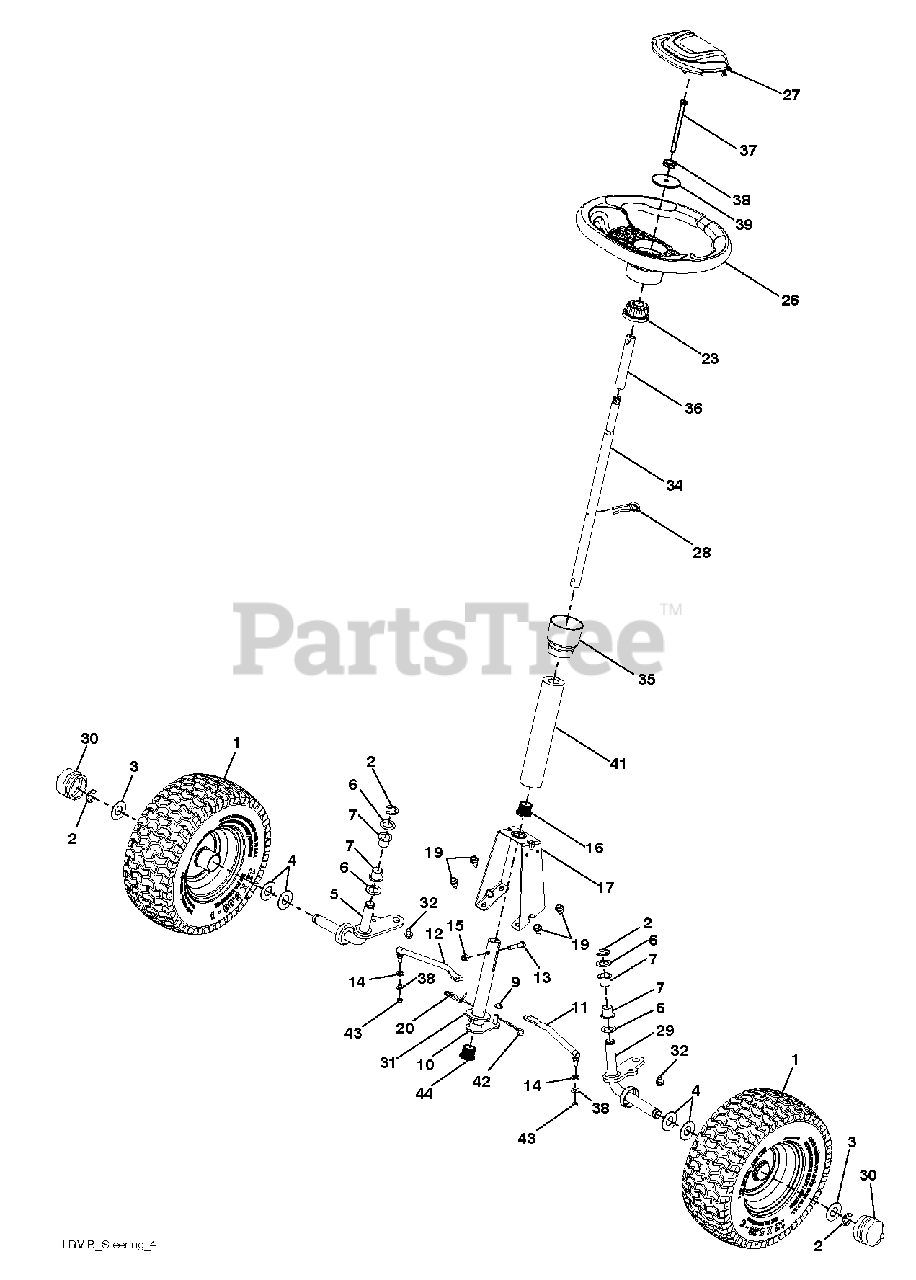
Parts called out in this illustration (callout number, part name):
1	WHEEL.TUBE.13X5.00-6.YELLOW
2	E-RING LT
3	WASHER.HARDENED
5	WELDMENT.SPINDLE.RH.LRV2
7	Steering Column Bearing
10	WELDMENT, LWR STRG SHAFT
11	SUBASM.LINKS.STEERING.LH.LRV2
12	SUBASM.LINK.STEERING.RH.LRV2
13	HEX BOLT
14	WASHER M
15	NUT.71038.31-18.HEX.NYLOCK
16	BUSHING.PLAIN.3/4 (76715)(2 2)
17	SUPPORT.STEERING.UPPER.LRV2
19	SCREW
20	CLIP.SPRING.STEERINGG
23	STEERING.WHEEL.ADAPTER
26	WHEEL.STEERING.MLT.BR.YEL/OVRM
27	CAP.WHL.STRNG.MULTI.BRND.YEL
28	RETAINER.CLIP.SPRING.S
29	WELDMENT.SPINDLE.LH.LRV2
30	CAP.AXLE.FRONT.YELLOW
32	Bolt, 5/16-18 X 1.25
34	SHAFT.STEERING.UPPER.LRV2
35	BOOT.LOWER.STEERING.WHEEL.LRVB
36	SHAFT EXTENSION STEERING
37	5/16-18X6.5.HEX.HEAD.SCREW
38	LOCKWASHER
39	WASHER.11/32
41	FOAM.SHAFT.STEERING
42	PIN.COTTER.5/64X3/4
43	NUT, CROWNLOCK
44	BUSHING, STEERING SNAP
